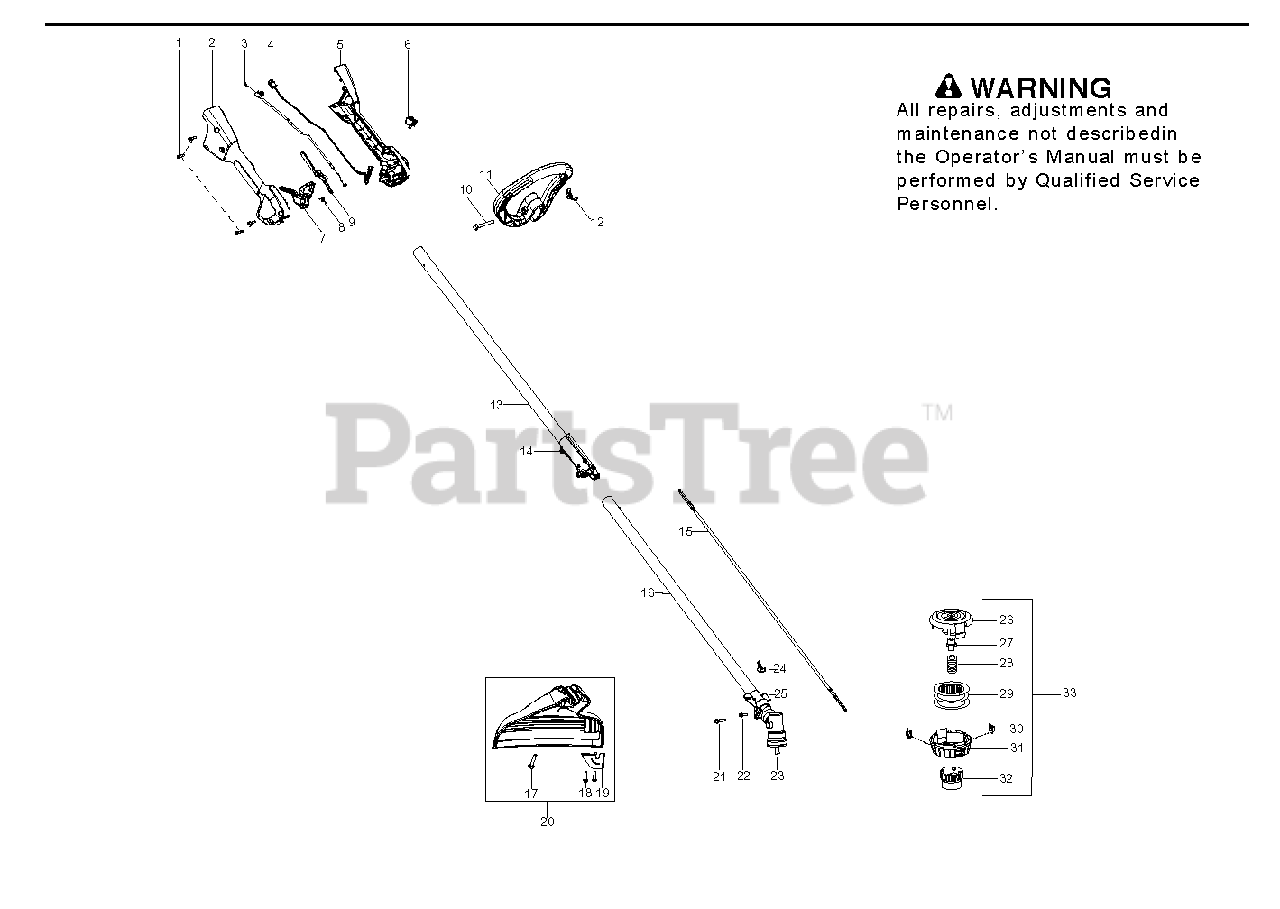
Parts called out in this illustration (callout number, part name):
1	SCREW M4 X 1.75 PT 16MM
2	THROTTLE HSG RH BLACK
3	ASSY THROTTLE CABLE TRMR
4	ASSY WIRE HARNESS
5	THROTTLE HSG LH BLACK
6	STOP SWITCH
7	TRIGGER YELLOW
8	SPRING TRIGGER
9	LOCKOUT YELLOW
10	BOLT 1/4-20 X 2 SQUARE
11	HANDLE ASSIST 1"
12	WINGNUT, TYPE 2
13	UPPER DRIVESHAFT
14	ASSY COUPLER BLACK
15	FLEXSHAFT
16	ASSY SHAFT LOWER STRAIGHT
17	BOLT, TYPE 2
19	LINE CUTTER
20	KIT LINE SHIELD STRAIGHT
21	SCREW - CARB. ADAPTOR
22	SCREW 8-16 X 9/16 (PLAS
23	GEARBOX 1
24	WINGNUT, TYPE 2
29	TNG VII SPOOL for PP125 .095"
30	EYELET (SUBS TO COVER W/EYELET
31	COVER
33	PPR TNG 7 .095 HEAD LH
